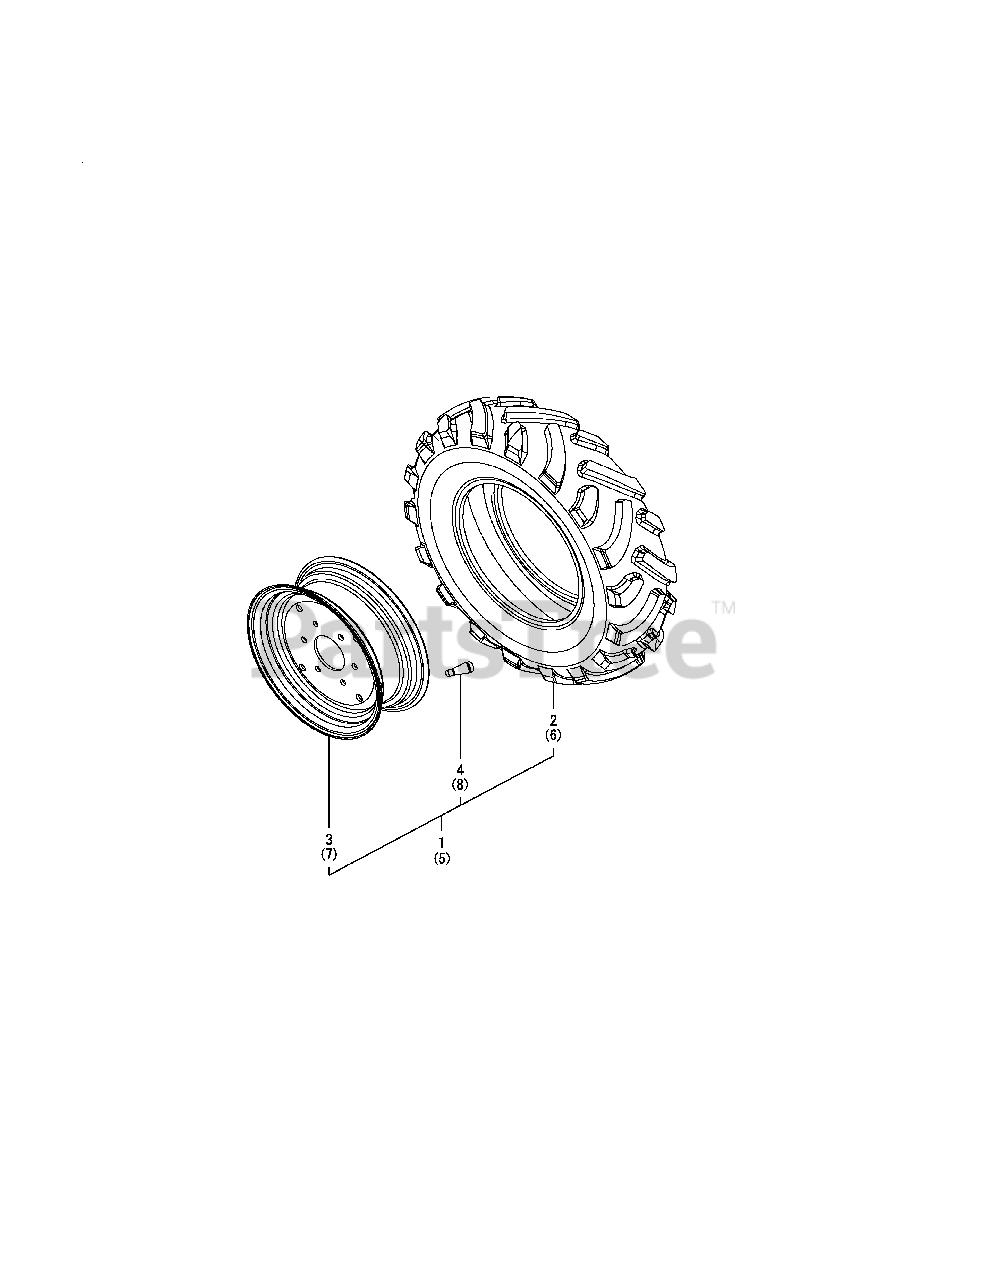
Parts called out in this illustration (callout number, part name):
1	TIRE ASM-FRNT AG LH
2	R1 TIRE-AG 7X14
5	TIRE ASM-FRNT AG RH
6	R1 TIRE-AG 7X14
